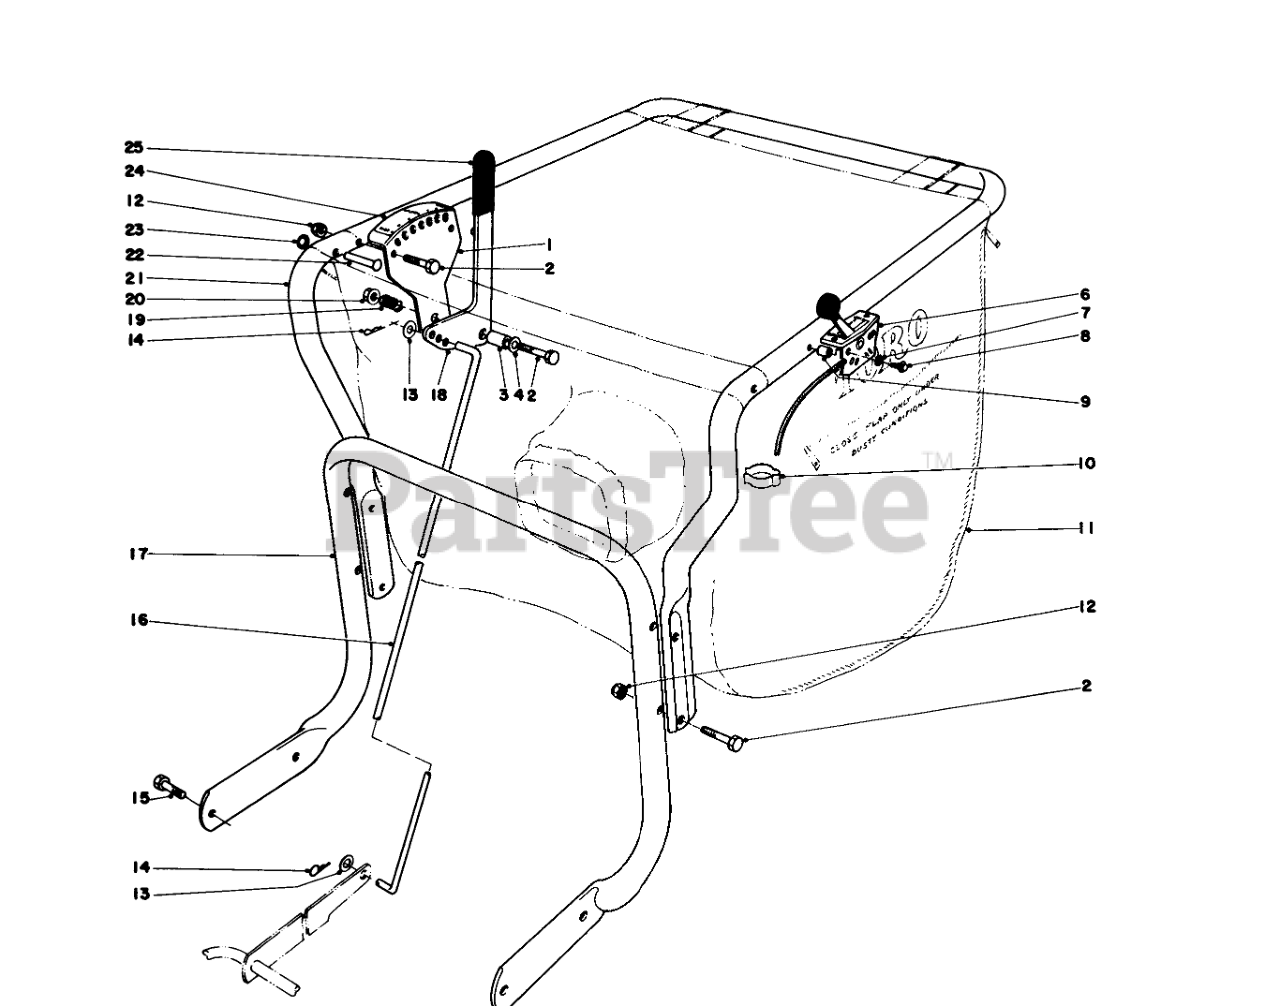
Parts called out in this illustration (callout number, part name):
1	Adjustment Bracket
2	SCREW-HH
3	SPACER
4	WASHER-FLAT
6	THROTTLE CONTROL
7	WASHER-LOCK, EXT
8	10-24 X 1 PAN HD SCR
9	SPACER
10	BODEN CLIP
11	Bag-Vacuum
12	NUT-LOCK, CONE
13	WASHER-FLAT
14	PIN-COTTER
15	SCREW-HH
16	HEIGHT ADJ. ROD
17	HANDLE
18	Handle-Adjustment
19	SPRING-COMPRESSION
20	NUT-HF
21	HANDLE-UPPER, VACUUM
22	RIVET
23	Push Nut
24	HT ADJ DECAL
25	GRIP-HANDLE
